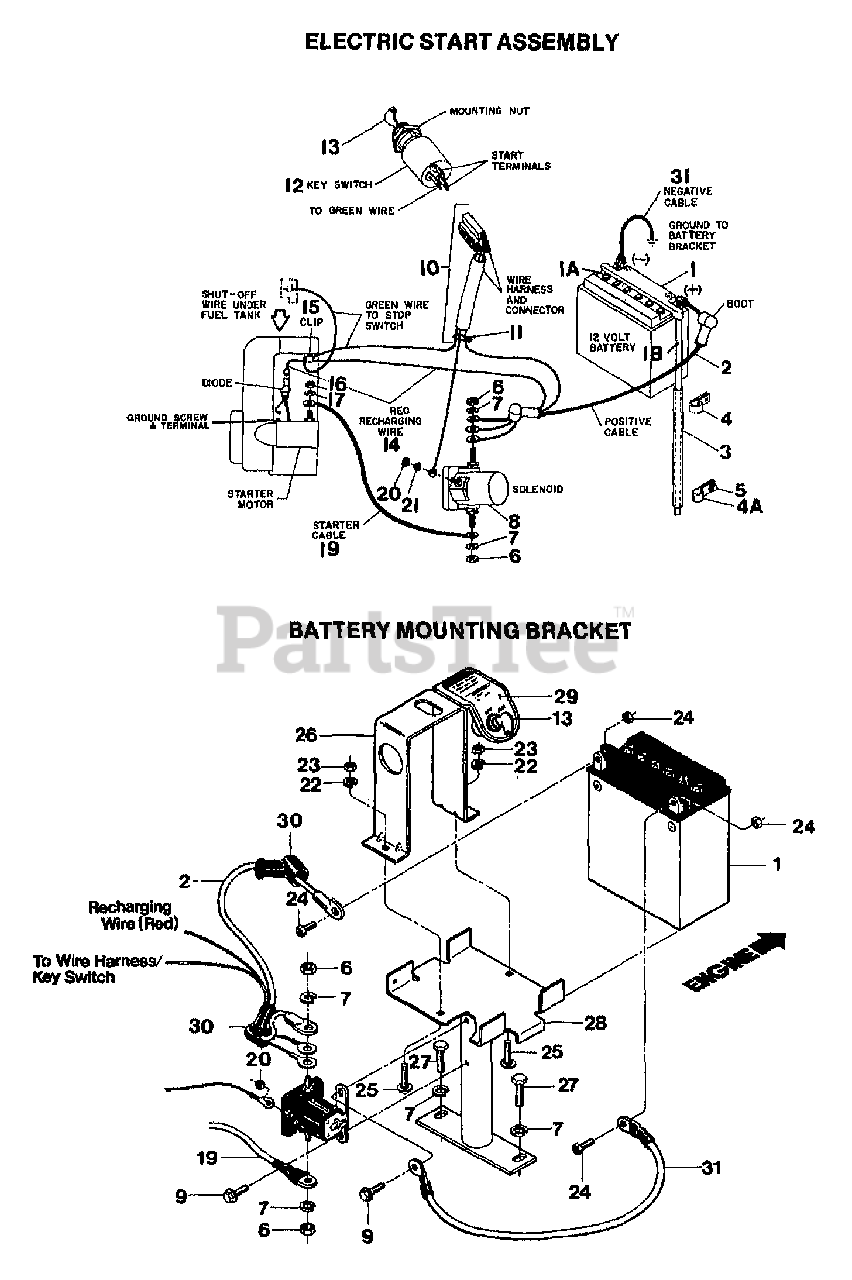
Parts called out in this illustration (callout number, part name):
1	BATTERY - 12 VOLT, 12 AMPERE
1A	CAP-YELLOW
1A	CAP-BATTERY WHITE (PONY)
1B	TUBE-VENT BATTERY/HSE
2	CABLE-BATTERY
3	TUBING-RUBBER (PLASTIC)
4	CLAMP -VENT TUBE (SMALL)
4A	CLAMP-VENT TUBE 9/16 OPC (LARGE)
5	SCR-HH 1/4-20X.625
6	NUT-HEX 5/16-24
7	WASHER-LK .312 ZP
8	KIT-SOL W/HDW (INCL. NUTS & WAHSERS FOR CABLES & WIRES)
9	SCR-HWH 1/4-20 X .5 STH
10	ASSM-HARNESS 2647/20857 - AVAIL. AS COMPLETE UNIT ONLY
11	TIE-TWIST LOCK (PLASTIC)
12	KEYSWITCH W/KEYS (PAIR OF KEYS INCL.)
13	KEYS(1 PAIR) FOR SWITCH
14	WIRE-RECHARGE 5&7 BRIGGS
15	CLIP-SPECIAL
16	NUT - HEX #10-24
17	LOCKWASHER - #10
19	CABLE-BATTERY
20	NUT-HH M10-32X.125
21	WASHER-EXTERNAL TOOTH 1
22	WASHER-LK .25 ZP
23	NUT-HEX 1/4-20 ZP
24	HDW PKG-BATTERY TERMINAL
25	SCR-CARR 1/4-20X1.25
26	PLATE-KEYSWITCH W/DECAL (INCL. #20820 DECAL)
27	SCR-HH 5/16-18X1.0 G5 ZP
28	BRKT-BATTERY OPC PNT
29	DECAL-KEYSWITCH
31	CABLE-BATTERY 13.5"
